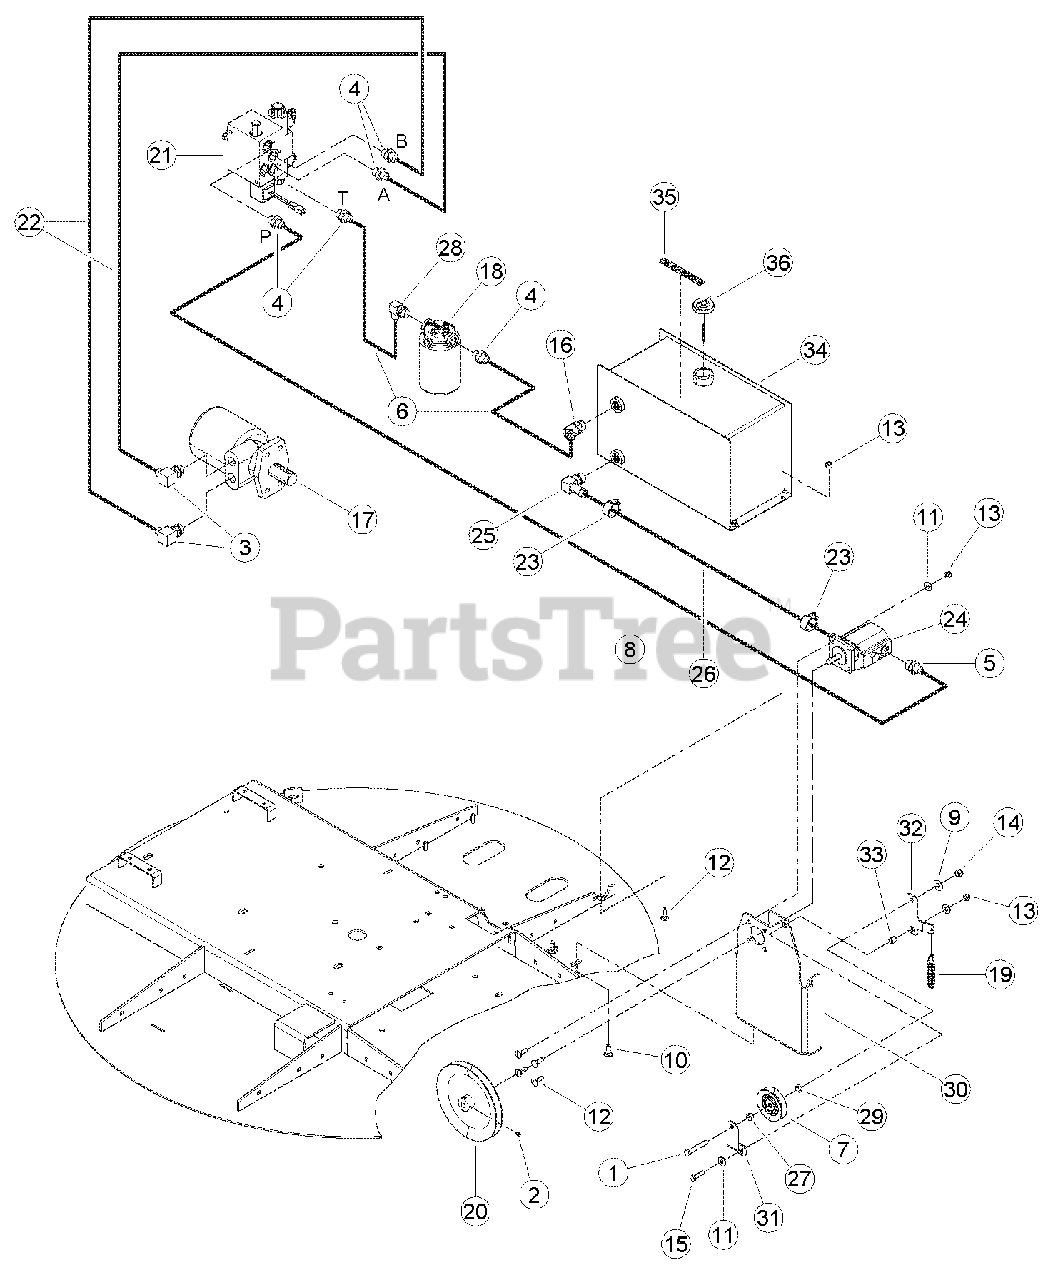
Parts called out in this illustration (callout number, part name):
1	BOLT, 3/8 X 2-1/4 HEX HD GR5 ZP
2	SETSCREW, 1/4-20 X 3/8 HSC CUP
3	ADAPTER, -10 MORING / -8 MJIC 90 DEG.
4	ADAPTER, -8 MORING / -8 MJIC
5	ADAPTER, -10 MORING / -8 MJIC
6	HOSE ASSY, -8 FMJIC / -8 FMJIC SW X 32"
7	IDLER, INSIDE
8	HOSE ASSY, -8 FJIC 90 DEG. SW / -8 FJIC SW 54"
9	WASHER, 3/8 FLAT ZP
10	BOLT, 3/8 X 1 CRG GR5 NC ZP
11	WASHER, 5/16 FLAT ZP
12	BOLT, 5/16 X 1 CRG GR5 ZP
13	NUT, 5/16 NE NYLOCK ZP
14	NUT, 3/8 NE NYLOCK ZP
15	BOLT, 5/16 X 1-1/4 HHCS GR5 NC ZP
16	ADAPTER, -10 MORING / -8 MJIC 45 DEG.
17	MOTOR, 45 CU. IN. HYDRAULIC
18	FILTER, SPIN-ON
19	CLAMP, 1-1/4" HOSE
20	SPRING, 3/4" OD EXTENSION
21	PULLEY, 7.5 OD X 1/2 IN BORE
22	ASSEMBLY, CHIPPER VALVE
23	HOSE ASSY, -8 FMJIC / -8 FMJIC 90 DEG. X 61"
24	PUMP, PB CW HI/LO .646 DISP.
25	ADAPTER, -10 MORING / .75 90 DEG. HOSE
26	HOSE, .75 X 19.75 100R4
27	BUSHING
28	ADAPTER, -8 MORING / -8 MJIC 90 DEG.
29	SPACER IDLER PIVOT
30	WELMENT, PUMP MOUNT
31	BRACKET, IDLER MOUNT
32	PLATE, IDLER MOUNT
33	SPACER, 1/2 OD X 14 GA X .49
34	ASSEMBLY, HYDRAULIC RESERVOIR, SERVICE PART
35	DECAL, HYDRAULIC FLUID
36	CAP, W/DIPSTICK
